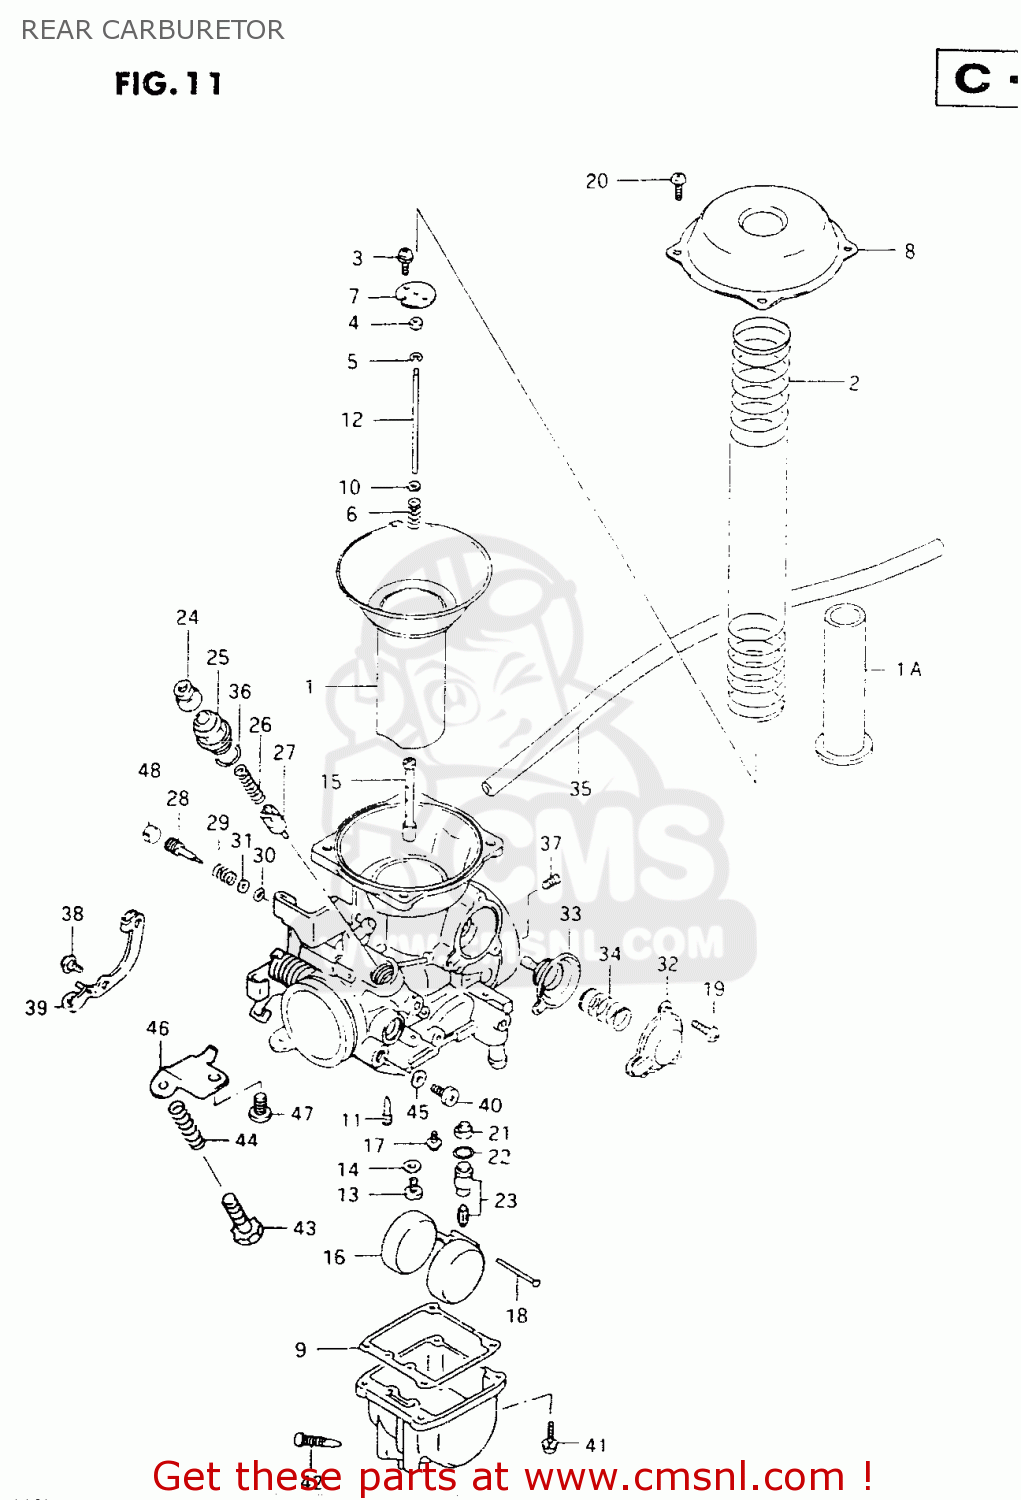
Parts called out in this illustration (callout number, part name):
1	DIAPHRAGM ASSY
1A	RING
2	SPRING,DIAPHRAGM
3	SCREW
4	RING
5	CLIP
6	SPRING
7	PLATE
8	COVER,DIAPHRAGM
9	GASKET,FLOAT CHAMBER (NAS)
10	WASHER
11	JET,PILOT
12	NEEDLE,JET
13	JET,MAIN
14	WASHER
15	JET,NEEDLE(P-3)
16	FLOAT
17	SCREW
18	PIN,FLOAT
19	SCREW
20	SCREW
21	FILTER
22	O-RING,NEEDLE VALVE
23	VALVE ASSY,NEEDLE
24	CAP
25	HOLDER,GUIDE
26	SPRING
27	PLUNGER,STARTER
28	SCREW,PILOT
29	SPRING
30	O RING,PILOT AIR SCREW
31	WASHER
32	COVER
33	DIAPHRAGM ASSY
34	SPRING
35	HOSE(5X8.2X600)
36	O RING
37	JET,PILOT(70)
38	SCREW
39	LEVER,ASSY
40	SCREW(5X6)
41	SCREW
42	SCREW,DRAIN
43	ADJUSTER
44	SPRING
45	GASKET,DRAIN PLUG (NAS)
46	BRACKET
47	SCREW
48	PLUG
